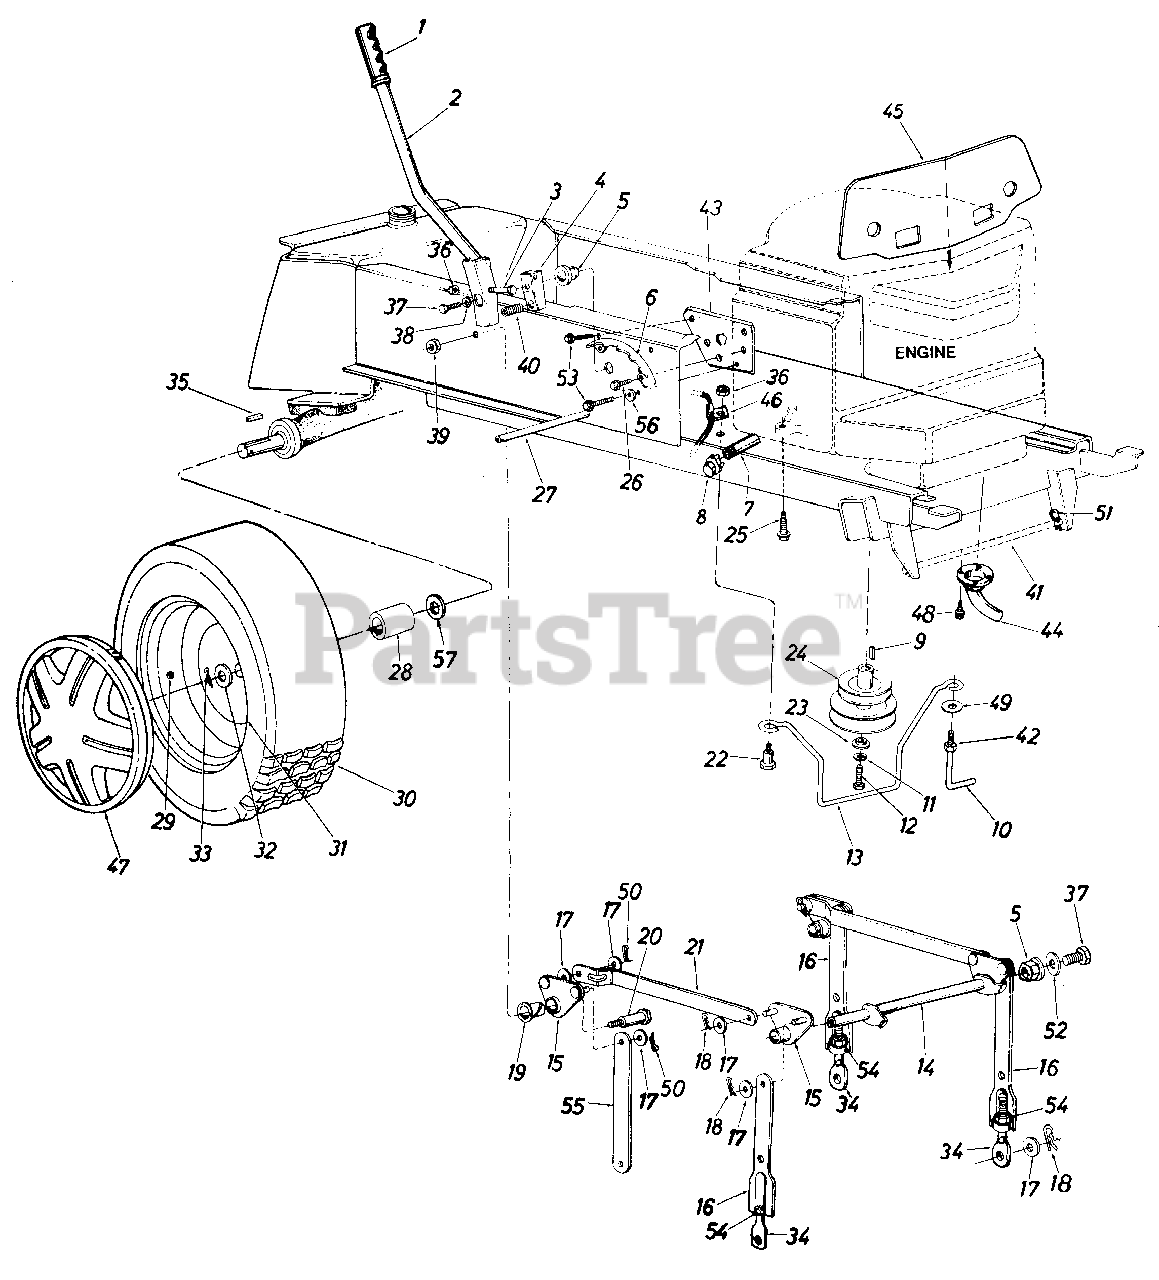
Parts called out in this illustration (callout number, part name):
1	Grip
2	Lift Handle Ass'y.
3	Hex Bolt 5/16-18 x 1.5" Lg.*
4	Lift Shaft Drive
5	Plastic Hex Brg. 518" I.D.
8	Pipe Cap 3/8-18 Npt.
9	Sq. Key 114" x 114" x 1.50"
10	Belt Guard Lock Pin
11	L-Wash. 7116" I.D.
12	Hex Scr. 7/16-20 x 1.50" Lg.
13	Belt Guard
14	Lift Shaft Ass'y.
15	Lift Pivot Brkt. Ass'y.
17	Fl-Wash. 112" I.D. x 1.00" O.D. x .090"
18	Hairpin Cotter
19	Nyliner 518" I.D. x .88" Lg.
20	Shld. Bolt 518" Dia. x .961' Lg. 3/8-16
23	Flat Wash. .44" I.D. x 1.25" O.D. x .171'
24	Two-Step Engine Pulley 4.75" & 5.56"
25	Hex Wash. Hd. Scr. 3/8-16 x 1.25" Lg.
26	Hex Thd. Rolling Scr. 5/16-18 x.75" Lg.
27	Running Board Rod
28	Spacer 1.0" I.D. x 1.25" O.D. x 2.9" Lg.
29	Air Valve
30	Rear Wheel Ass'y. Comp.
33	Cotter Pin 3/16" Dia. x 1.50" Lg.
34	Eye Bolt Adj. Link '/2-13 Thd.
35	Sq. Key 1/4 x 3.0"
36	Hex Cent. L-Nut 5/16-18 Thd.
37	Hex Scr. 5/16-24 x .62" Lg.
38	L-Wash. 5/16" I.D.
39	Hex Top L-Nut 3/8-16 Thd.
40	Compression Spring
41	Deck Connecting Rod
42	Hex Nut 5/16-24 Thd.
45	Heat Shield
46	Mounting Clamp
47	Hub Cap Rear
48	Hex Wash. Hd. AB-Tap Scr. #10 x .50" Lg.
49	Bell-Wash...39" I.D.
50	Cotter Pin .09 Dia. x 1.0" Lg.
51	Int. Cotter Pin
52	Flat Wash. .34" I.D. x 1.12" O.D. x .125"
53	Hex Wash. Hd. AB-Tap Scr. 5/16-24 x .5" Lg.
54	Hex Nut 1/2-13 Thd .
56	Fl-Wash....344" I.D.
57	Fl-Wash. 1.0" I.D.
